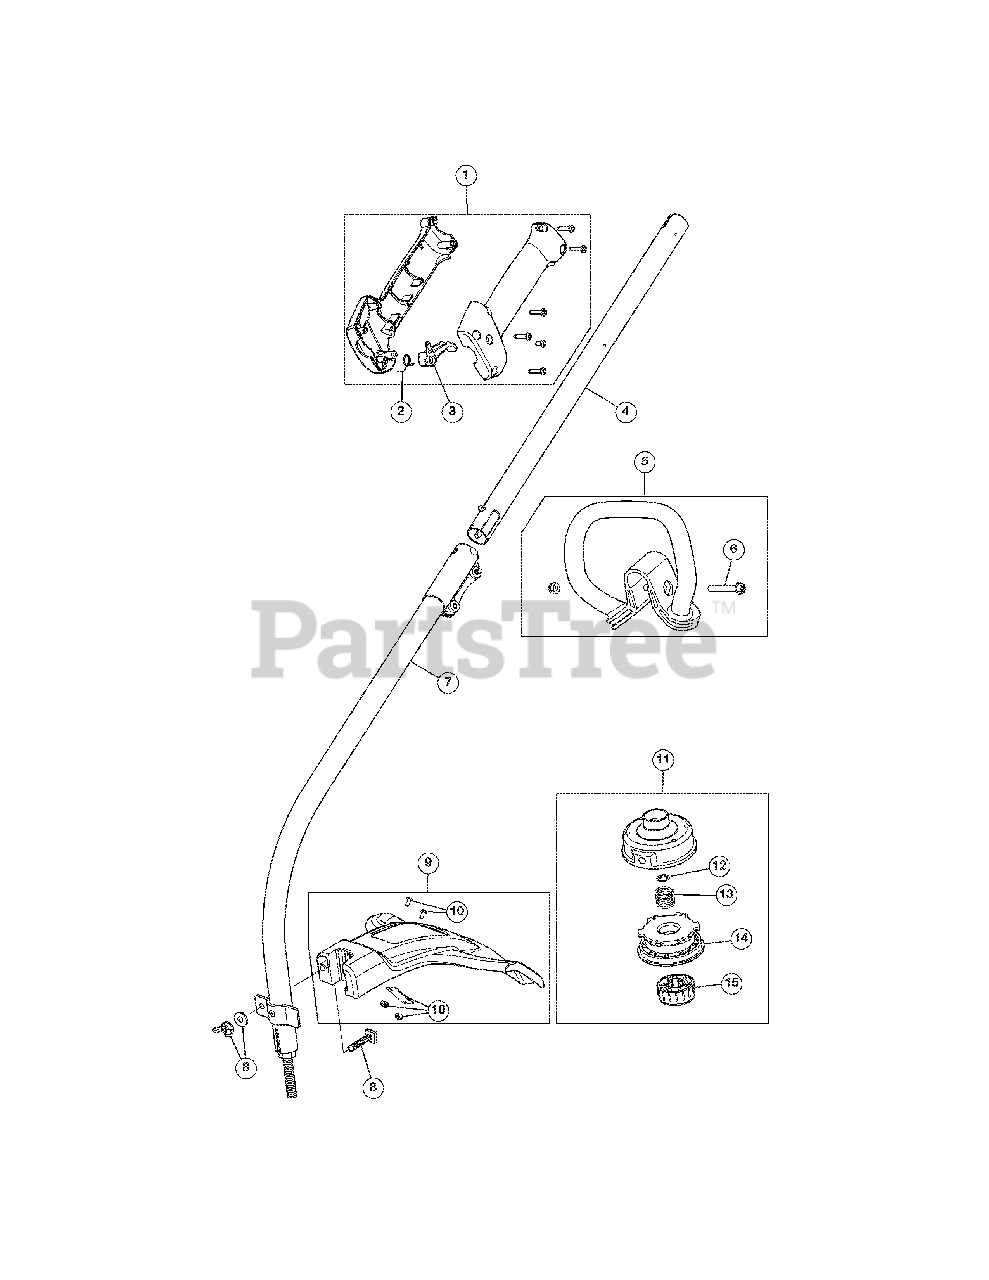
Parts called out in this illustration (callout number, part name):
1	Throttle Housing Assembly (Incl. 2 & 3)
2	Throttle Trigger Spring
3	Throttle Trigger
4	Upper Shaft Housing Assembly
5	D-Handle (Incl. 6)
6	D-Handle Bolt
7	Lower Shaft Housing Assembly
8	Shield Mounting Hardware
9	Shield Assembly (Incl. 10)
10	Blade Assembly
11	Outer Spool Assembly (Incl. 12)
12	Retainer
14	Inner Reel
15	Bump Head Knob Assembly
